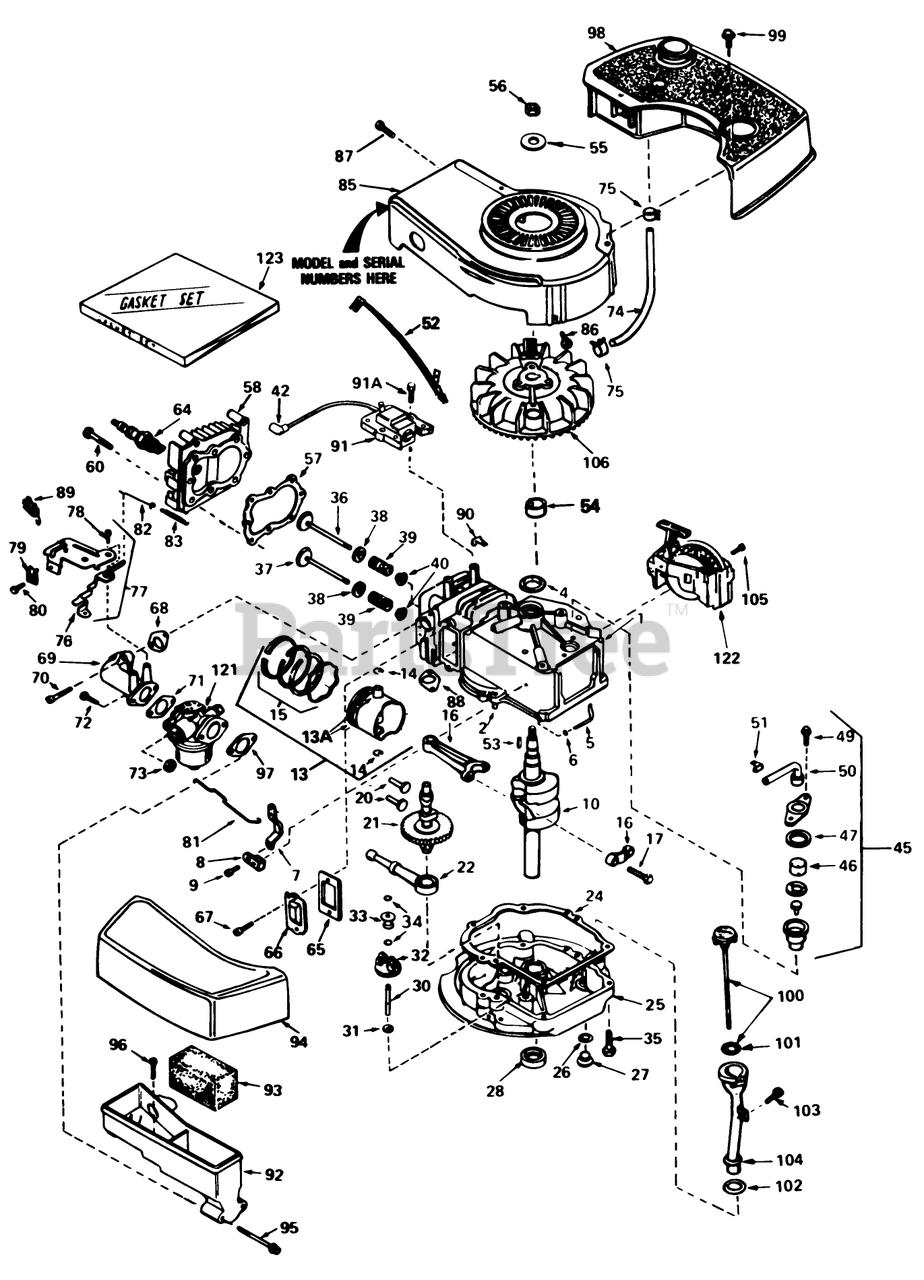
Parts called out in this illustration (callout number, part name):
1	Cyiinder Assy. (Incl. Ref. #2, 4 105)
2	Pin-Dowel
4	Seal-Oil
5	Rod, Governor (Incl. No. 36)
6	Washer-Flat
7	Governor Lever
8	Clamp-Lever, Governor
9	Screw
10	Crankshaft
13	Piston, Pin Ring Assy. (Std.) (Incl. Ref. #13A, 14 15)
13	Piston, Pin Ring Assy. (.010 oversize) (Incl. Ref. #13A, 14 15)
13	Piston, Pin Ring Assy. (.020 oversize) (Incl. Ref. #13A, 14 15)
13A	Piston Pin Assy. (Incl . Ref. . #14) (Std.)
13A	Piston Pin Assy. (Incl. Ref. #14) (.010 Oversize)
13A	Piston Pin Assy. (.020 oversize) (Incl. Ref. #14)
14	Ring-Retaining, Piston Pin
15	Ring Set (Std.)
15	Ring Set (.020" OS)
15	Ring Set (.010" OS)
16	Rod Assy., Connecting (Incl. Ref. #17)
17	Bolt-Rod, Connecting
20	Lifter-Valve
21	Camshaft(Mech.Comp. Release)
22	Oil Pump ASM
24	Gasket, Mounting
25	Flange Assy., Mounting (Incl. Ref. #26thru 30)
26	Gasket-Oil Drain
27	Plug Oil Drain
28	Seal Oil
30	Shaft-Governor
31	Washer-Flat
32	Governor Gear ASM
33	Spool-Governor
34	Ring-Retaining
35	Screw (1/4-20 x 1-1/4)
36	Valve, Intake (Std.) (Incl. Ref. #40)
36	Valve, Intake (1/32" oversize)(Incl. No. 40)
37	Valve, Exhaust (Std.)(Incl. No. 40)
37	Valve, Intake (1/32" oversize)(Incl. No. 40)
38	Cap-Upper Valve Spring
39	Spring-Valve
40	Cap-Valve, Spring
42	Cover-Spark Plug
45	Breather Assy. (Incl. Ref. #46 thru 51)
46	Element-Breather
47	Gasket-Breather
49	Screw (10-24 x 9/16)
50	Tube, Breaker
51	Clip, Breather
52	Wire-Ground
53	Key-Flywheel
54	Spacer
55	Washer-Belleville
56	Nut-Flywheel
57	63573 GIL 42 SNWTHW
58	Head-Cylinder
60	Screw (5/16-18x1-1/2)
64	Plug, Spark (J17LM or equiv.)
64	Plug, Spark (Champion RCJ-8)
65	Gasket-Breather
66	Cover-Valve
67	Screw
68	Gasket-Intake
69	Pipe, Intake (Incl. No. 68)
70	Screw (1/4-20 x 1)
71	Gasket-Carburetor
73	Nut and Lock Washer (1/4-28)
74	Line-Fuel
75	Clamp-Line, Fuel
76	Lever Control
77	Control Assy., Speed (Incl. Nos, 76, 78 89)
78	Screw, Hex Washer Hd Shoulder Self-Tap
79	Conduit
80	Screw (10-32 x 3/8)
81	Link-Throttle
82	Link Governor Spring
83	Spring Governor
85	Housing-Blower
86	Screw (1/4-20x19/32)
87	Screw (10-24 x 9/16)
88	Gasket Exhaust
89	Terminal
90	Clip-Wire
91	Solid State
91A	Screw
92	Body Air Cleaner
93	Filer, Air
94	Cove, Air Cleaner
95	Screw Fil Hd.
96	Screw, Hex Hd.
97	Gasket-Air Cleaner
98	Tank-Fuel
99	Screw (10-32 x 35/64)
100	Dipstick, Oil (Incl. Ref. #101)(Twist Lock)
101	O-Ring
102	Gasket
103	Screw (10-32 x 1/2)
104	Tube-Oil Fill
105	Screw (1/2-20x5/8)
106	Flywheel
121	Carburetor (Incl. Ref. #71)
122	Starter-Sidemount
123	Gasket Set
